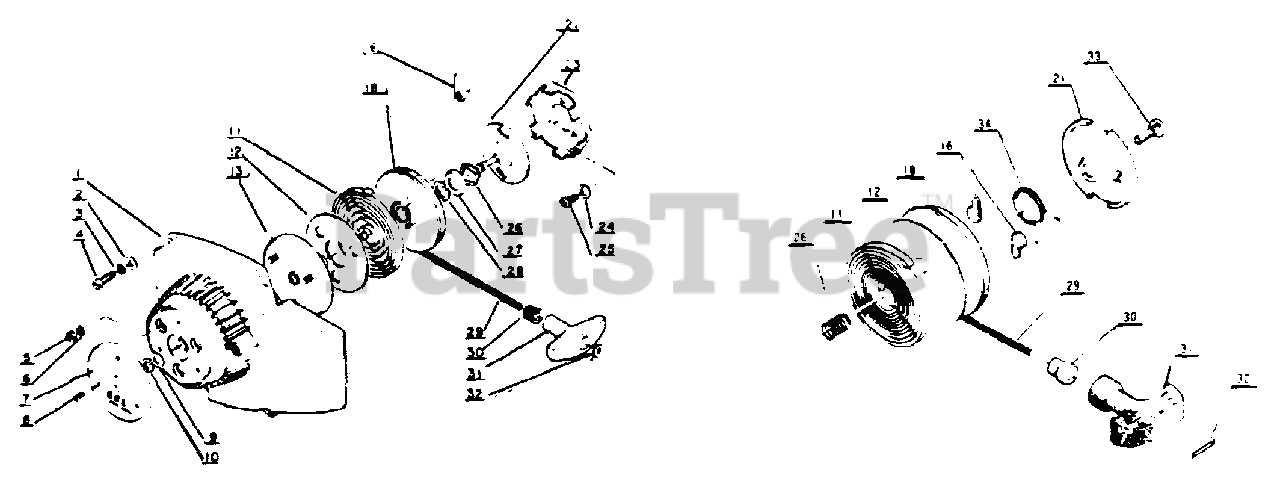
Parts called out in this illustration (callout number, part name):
1	CASE, STARTER
2	WASHER
3	WASHER - SPRING
4	SCREW
5	NUT
6	WASHER, SPRING 5
7	NAME PLATE
8	SCREW
9	WASHER
10	RING, RETAINING - 6
11	SPRING, RECOIL
12	PLATE, STARTER
13	RETAINER, SPRING
16	RATCHET
18	REEL, ROPE
21	PLATE, GUIDE
23	PAWL CATCHER
24	WASHER, SPRING 6
25	BOLT - 6×14
26	WASHER
27	WASHER
28	RING, RETAINING
29	ROPE, STARTER
30	GUIDE, ROPE
31	GRIP, STARTER
32	WASHER
34	SPRING, RETURN
